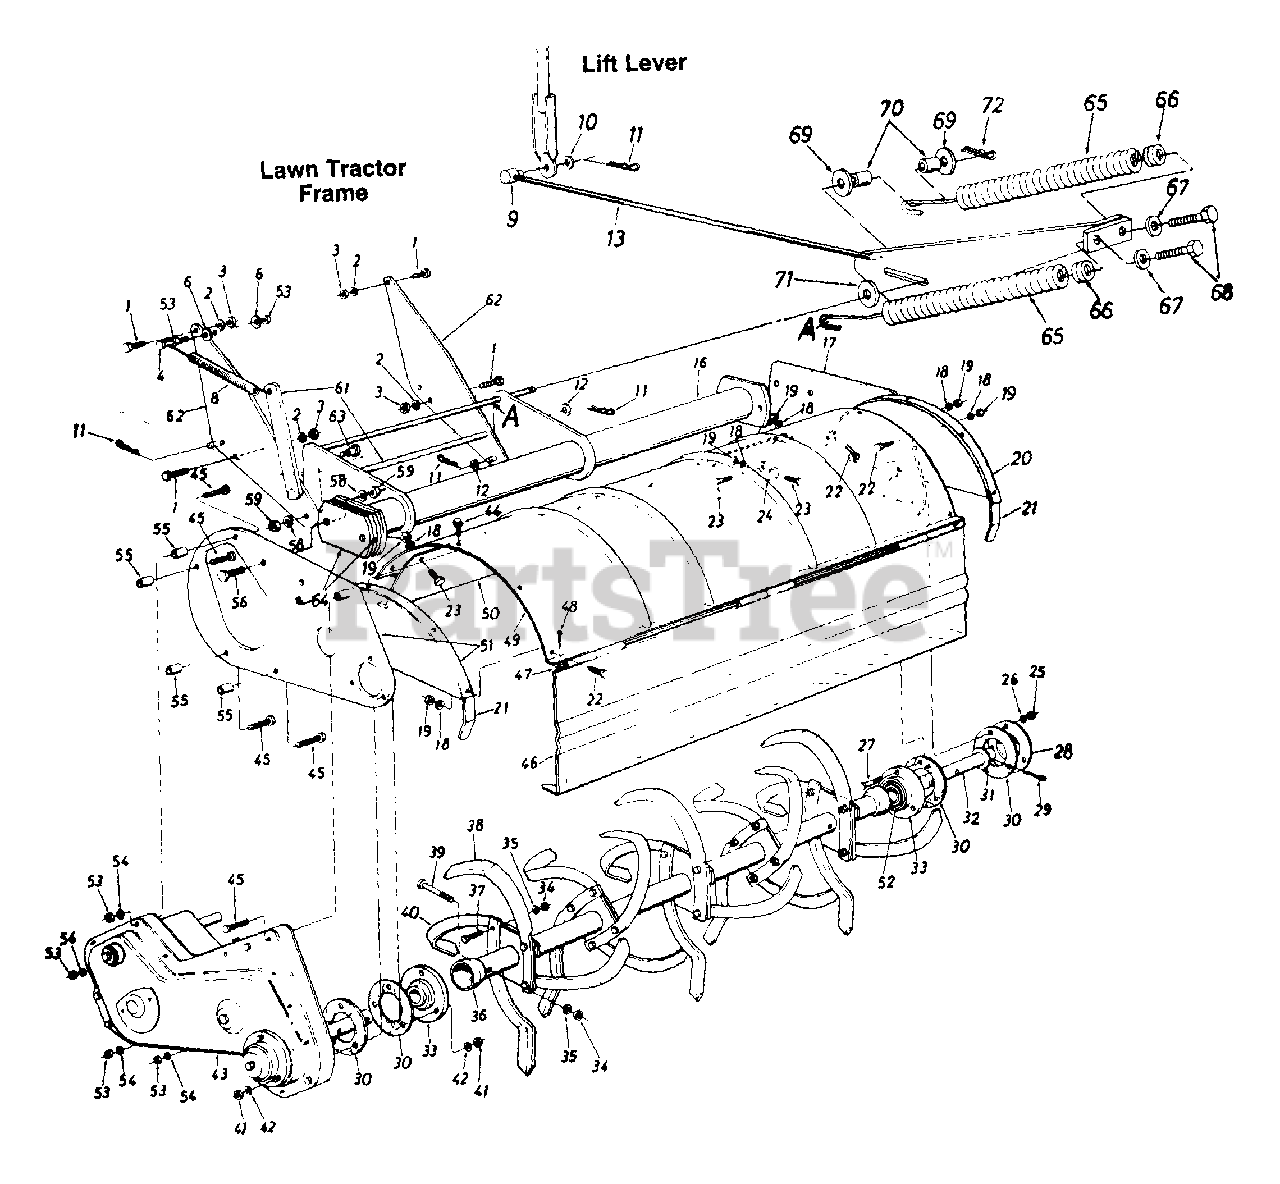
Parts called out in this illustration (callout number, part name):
1	Hex Bolt 3/8-24 x .88" Lg.
2	L-Wash. 3/8" I.D.- H.D.
3	Hex Nut 3/8-24 Thd.
4	Hex Bolt 1/4-20 x 1.25" Lg.
6	Bell-Wash. 1/4" I.D.
8	Ext. Spring 7.75" Lg.
9	Adjustment Ferrule 1/2-13 Thd.
10	Fl-Wash..64" I.D. x 1.24" O.D. x .06"
11	Intern. Cotter Pin 1/2" Dia.
12	Fl-Wash..51" I.D. x 1.0" O.D. x .06"
16	Pivot Bracket Assembly
19	Hex Nut 5/16-24 Thd.
23	Hex Bolt 5/16-24 x .62" Lg.
24	Chute Pivot Bracket
25	Hex L-Nut 5/16-18 Thd.
27	Hex Bolt 5/16-18 x 1" Lg. (Grade 5)
30	Gasket for Brg. Housing
31	Fl-Wash. 1.25" I.D. x 2.0" O.D. x .06"
32	Tine Shaft 1.25" Dia. x 6.25" Lg.
33	Bearing Housing w/Bearing
43	Chain Case Ass'y. Comp.
44	Hex TT-Tap Scr. 5/16-18 x .62" Lg
45	Hex Bolt 1/4-20 x 2 75" Lg.
48	Cotter Pin 1/8" Dia. x 1" Lg.
53	Hex Nut 1/4-20 Thd.
54	L-Wash. 1/4" I.D.
55	Spacer.28" I.D. x.62" O.D. x .9" Lg.
56	Hex Bolt 1/2-20 x 1.5" Lg.
58	L-Wash. 1/2" I.D.
59	Hex Nut 1/2-20 Thd.
61	Idler Brkt. Support Arm Ass'y.
64	Support Plate
65	Helper Spring
66	Spring Insert
67	Fl-Wash..34" I.D. x .68" O.D.
68	Hex Bolt 5/16-18 x 3.25" Lg.
69	Fl-Wash..51" I.D. x 1.5" O.D.
70	Split Spacer .505" I.D. x .57" Lg.
71	Fl-Wash..531" I.D. x 1.25" O.D.
72	Internal Cotter Pin 1/2" Dia.
